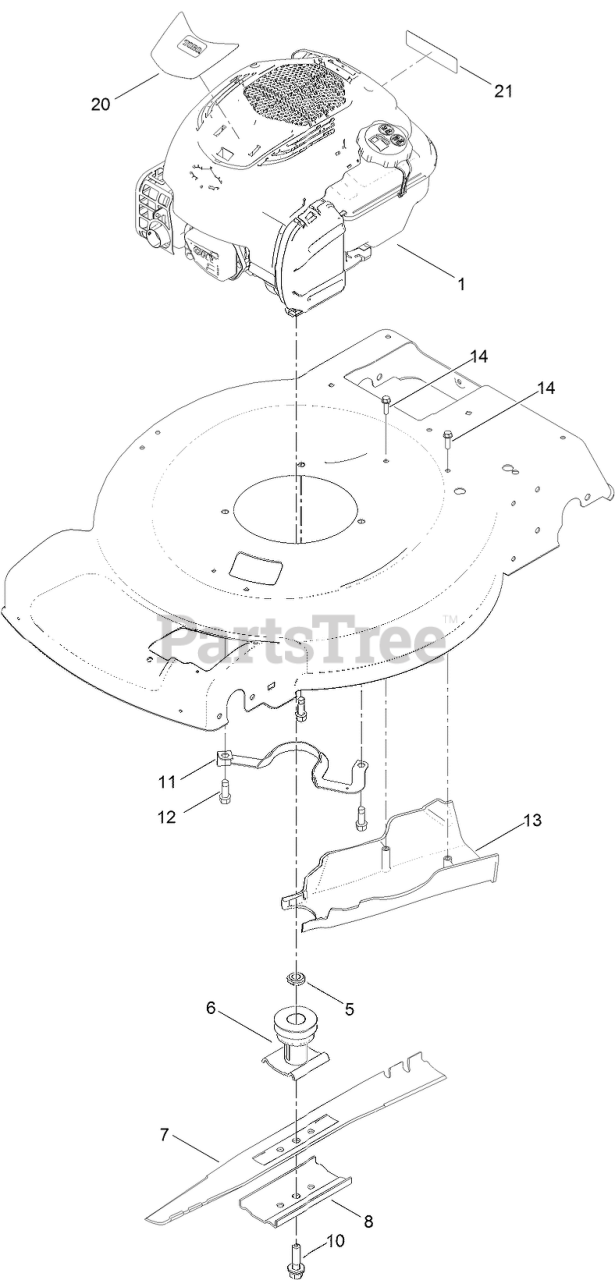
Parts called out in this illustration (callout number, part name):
5	Spacer-Driver
6	DRIVER-BLADE
7	BLADE-22 INCH
8	SUPPORT-BLADE
10	BOLT-BLADE
11	GUIDE-BELT
12	SCREW-TAPTITE
13	COVER-BELT, REAR
14	SCREW-HWH
20	DECAL-SHROUD, BRIGGS
21	DECAL-ARRESTER, SPARK
